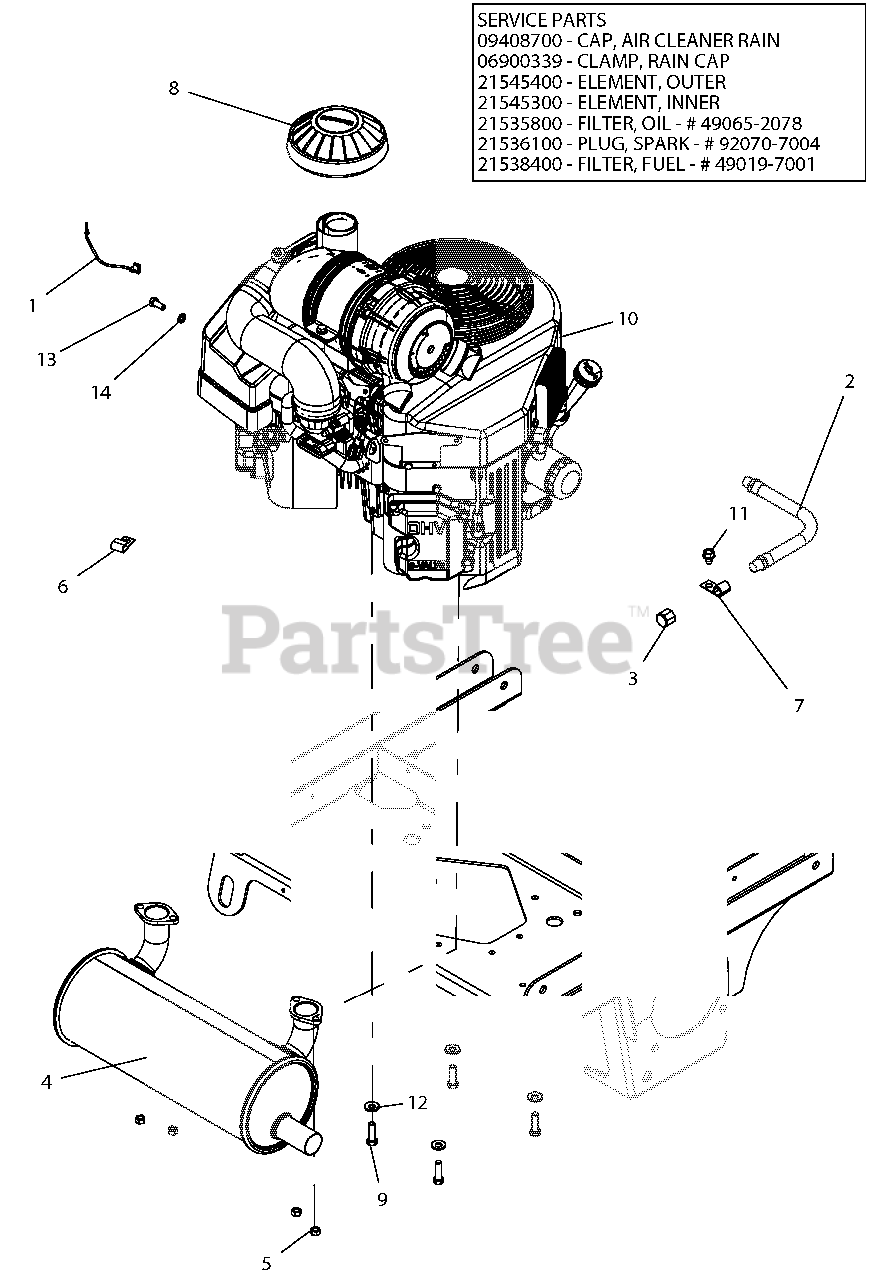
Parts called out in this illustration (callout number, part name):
1	LEAD - STARTER SOLENOID
2	HOSE, HYD .38-11-0K M6N0-M6N0
3	PIPE, CAP 3/8 NPT FEMALE
4	MUFFLER - 34HP KAWASAKI VERT
5	NUT-LK-TOP M8-1.25 YWZC
6	CLAMP, J
8	CAP, AIR CLEANER INTAKE (2")
9	BLT-HEX .38-16X1.25 GR5 YWZC NYTORQ
10	ENGINE, KAWASAKI FX921
11	SCR-TAP .38-16X.50 HWH TR YWZ
12	WSHR, 3/8" SPRING DISC
13	@BLT-HEX M8-1.25X20 YWZC
14	WSHR-LK .31X.078 REG YWZC
